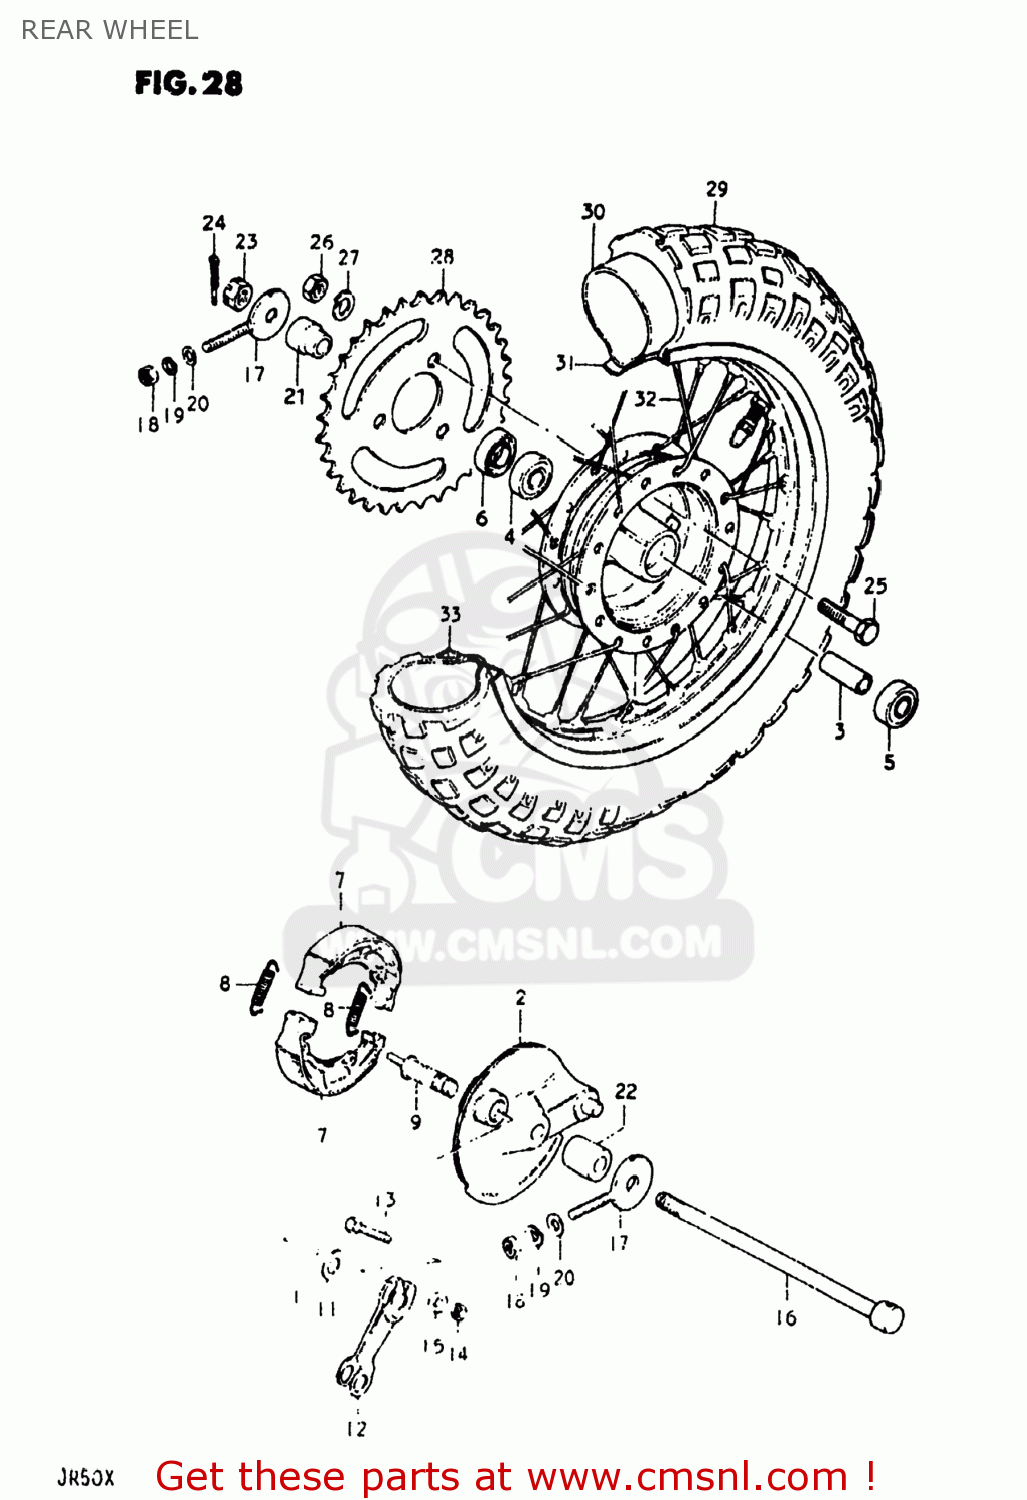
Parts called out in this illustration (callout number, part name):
1	HUB,RR WHEEL
2	PANEL,RR BRAKE ANCHOR
3	SPACER (10.2X16X55)
4	BALL BEARING K
5	BEARING
6	SEAL,OIL(15X27X6)
7	SHOE,BRAKE
8	SPRING(L:34)
9	CAM,FRONT BRAKE
10	O RING(D:2.4,ID:9.8)
11	WASHER (10.5X18X1)
12	LEVER,RR BRAKE CAM
13	BOLT
14	NUT
15	WASHER
16	AXLE,RR
17	ADJUSTER,CHAIN
18	NUT
19	LOCK WASHER
20	WASHER
21	SPACER,RR AXLE,L
22	SPACER,RR AXLE,R
23	NUT
24	COTTER PIN
25	BOLT
26	NUT
27	LOCK WASHER
28	SPROCKET,RR
29	TIRE
30	TUBE,INNER
31	PROTECTOR,INNER TUBE
32	SPOKE SET,RR
33	RIM,WHEEL
